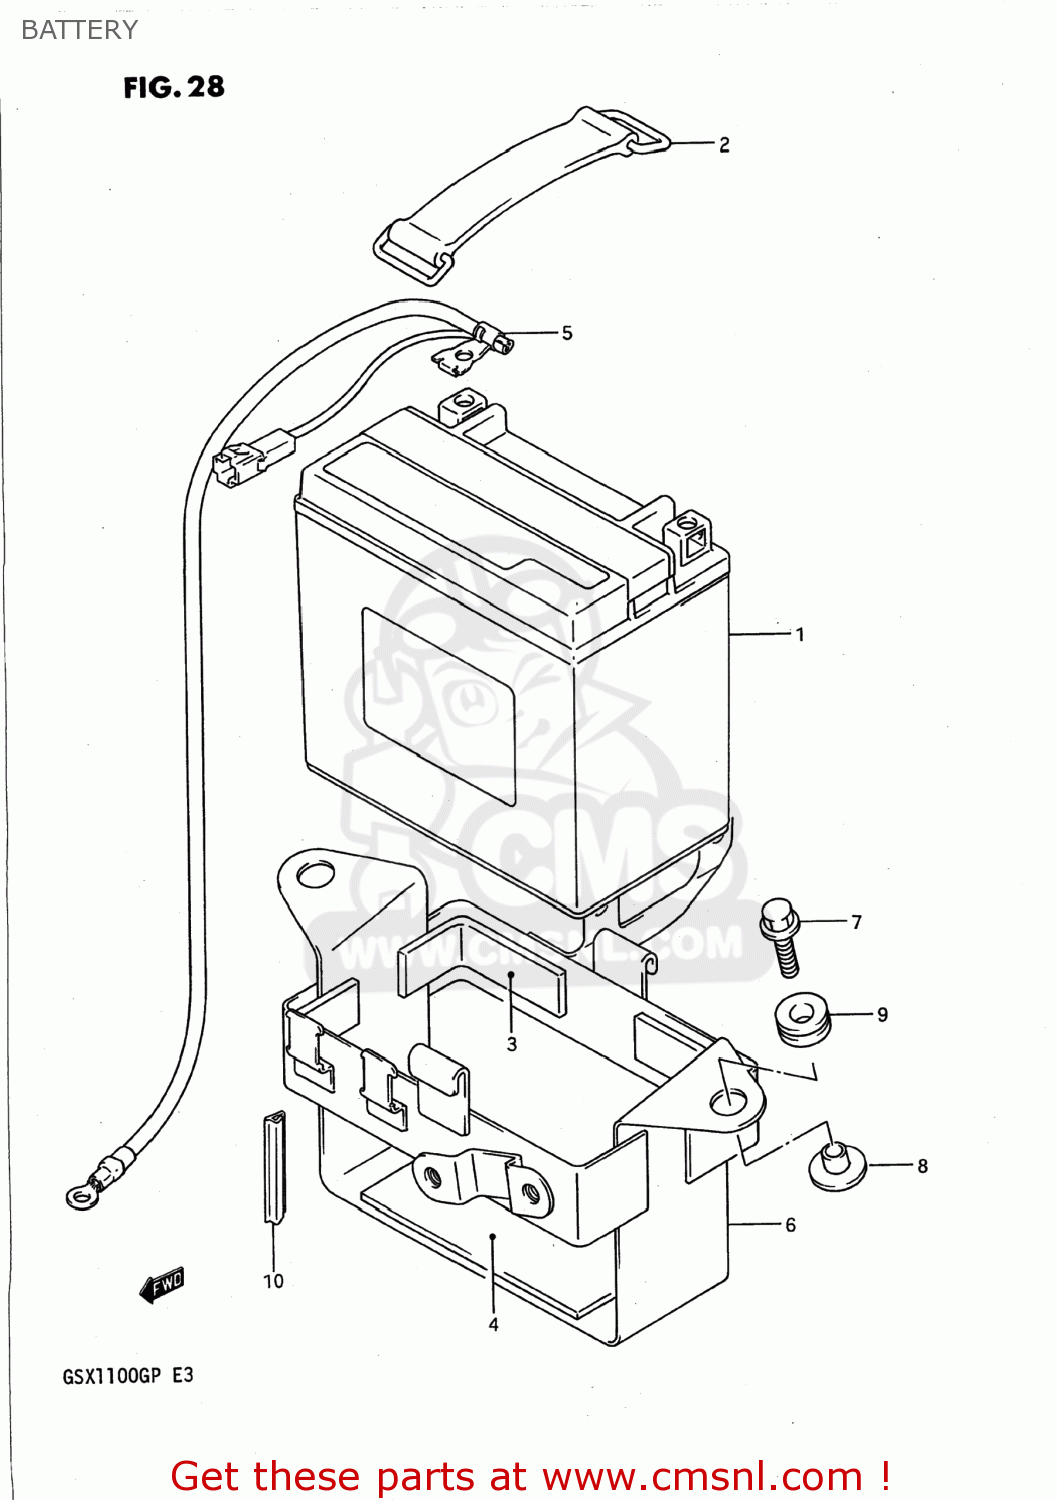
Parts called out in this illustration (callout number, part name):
1	BATTERY ASSEMBLY
2	BAND
3	PROTECTOR,20X9
4	PROTECTOR(170X95X3.0)
5	WIRE,BATTERY MINUS LEAD
6	HOLDER,BATTERY
7	BOLT
8	PLATE,BATTERY HOLDER
9	CUSHION
10	MOLDING
